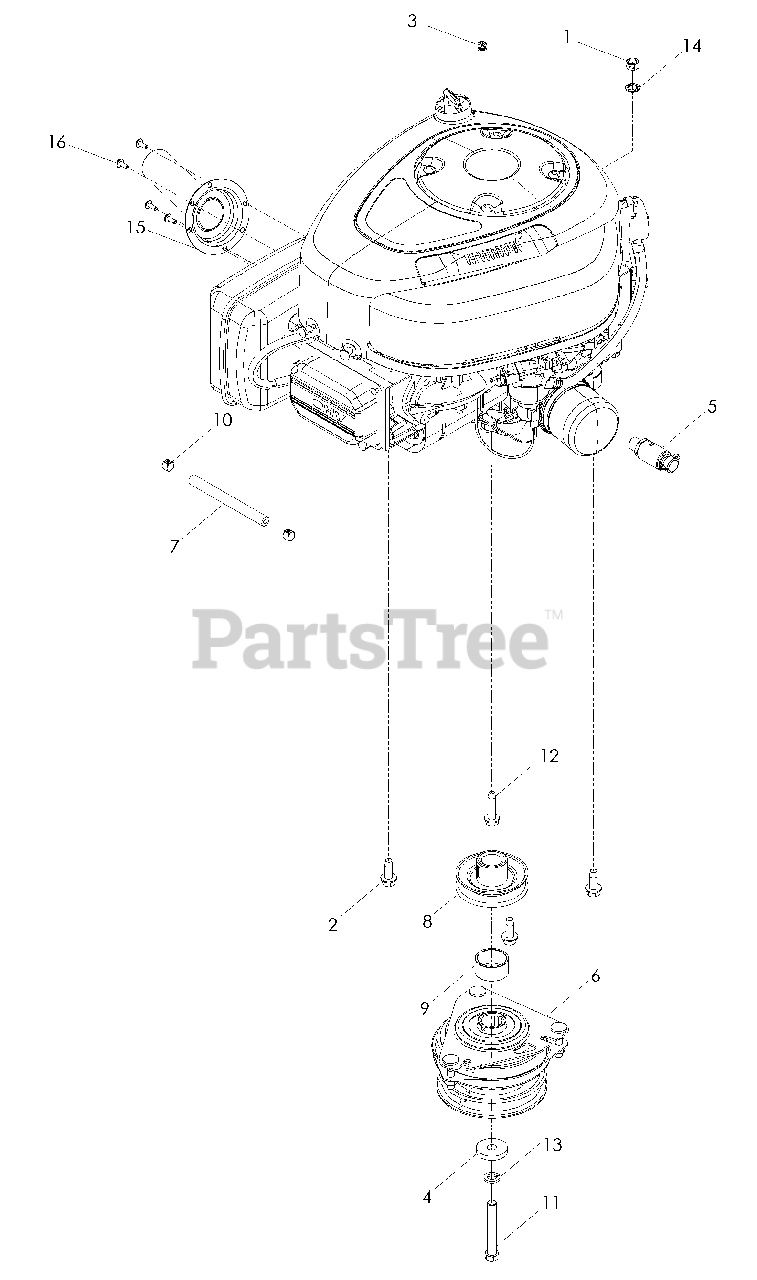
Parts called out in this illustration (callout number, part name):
1	NUT, 3/8-16 HEX CNTRLK
2	BOLT, 3/8-16 x 1, THD FRM
3	NUT, 1/4-20, THIN, NYLOC
4	CLUTCH WASHER
5	OIL DRAIN FITTING
6	CLUTCH
7	FUEL LINE, 5"
8	PULLEY, ENGINE
9	SPACER, ENGINE PULLEY
10	CLAMP, HOSE
11	HCS, 7/16-20 x 3
12	BOLT 3/8-16 x 1.5 THD FRM
13	WASHER 7/16 SLW ZD
14	WASHER, 3/8
15	EXTENSION, MUFFLER
16	SCREW, #10 -16 x 1/2
